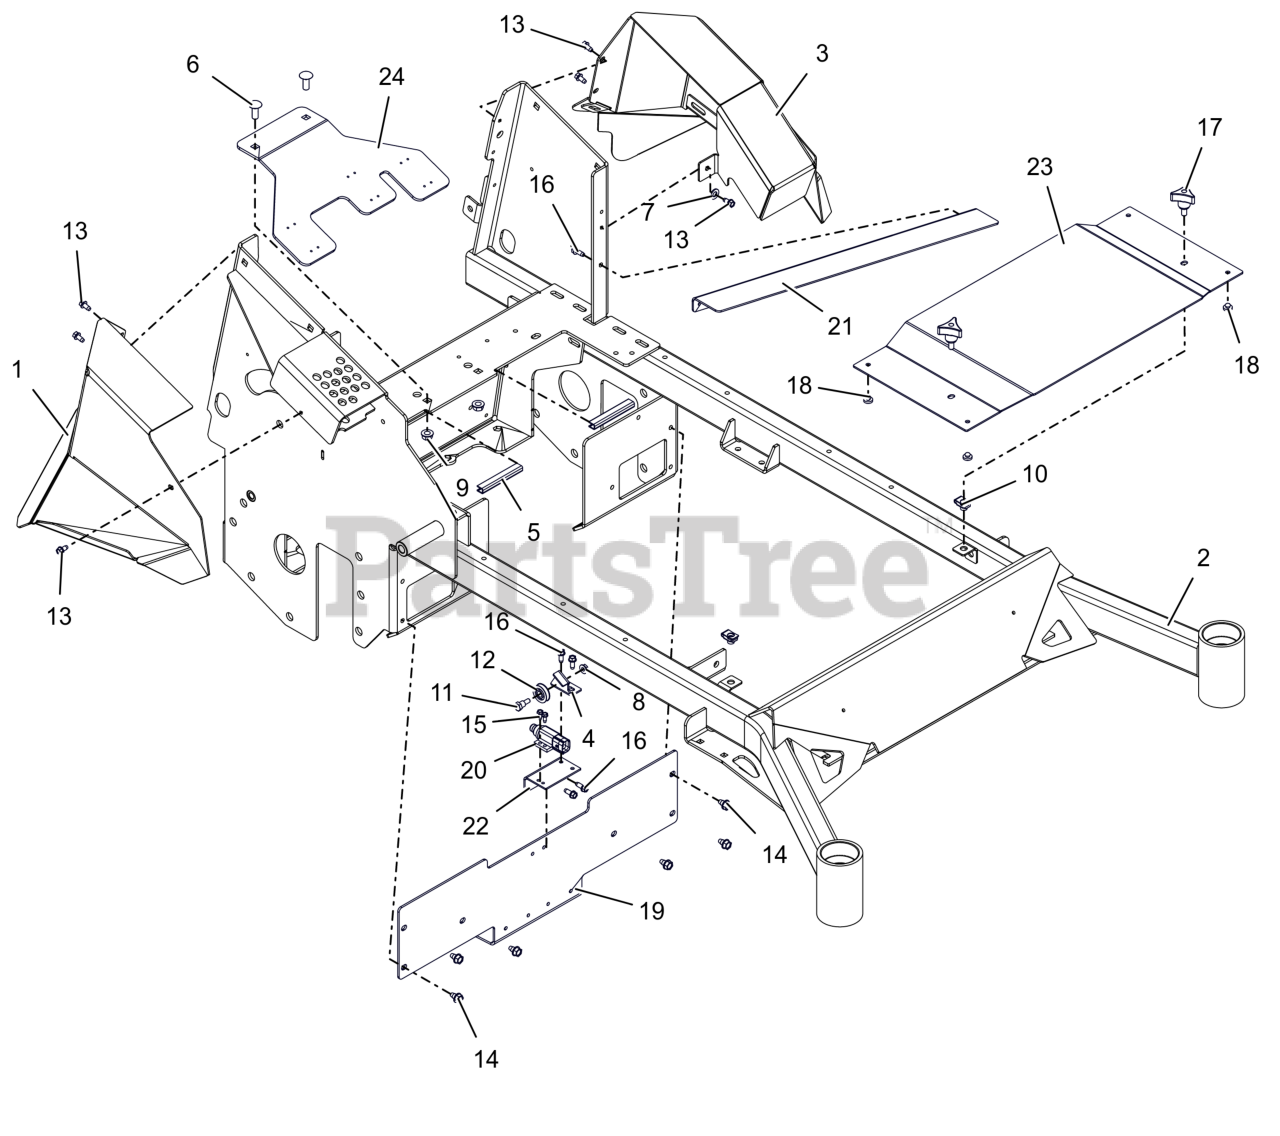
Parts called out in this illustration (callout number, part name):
1	WLDMT, RH FENDER (BLACK)
2	WLDMT- PROSTANCE MAIN FRAME
3	WLDMT, LH FENDER (BLACK)
4	BRKT, CABLE PULLEY
5	STRIP, COWL
6	BLT,RHSSN .38-16X1.00 G5 ZCC
7	WSHR,FLT .344X.688X.065 ZCC
8	NUT-LK-CTR-FLG .25-20 ZC120
9	NUT-LK-CTR-FLG .375-16 GF ZCC
10	NUT-CLIP RETAINER 5/16-18X.56
11	BOLT, SHLDR -.375 X .375 X .25-20
12	PULLEY, CABLE
13	SCR-TAP .25-20X.50 HWH ZCC
14	SCR,TAP .312-18X.50 HWH TR ZCC
15	SCR,TAP #10-24X.50 HWH TR ZCC
16	SCR,TAP .25-20X.625 HWH ZCC
17	KNOB,WING STUD 5/16-18 X .75
18	BUMPER GROMMET
19	PLATE- FRONT FRAME
20	SWITCH, SEALED PLUNGER
21	BRKT, DRIP EDGE (BLACK)
22	BRKT- LOWER BRAKE RELEASE
24	BRKT, ANDERSON MTG (ORANGE)
